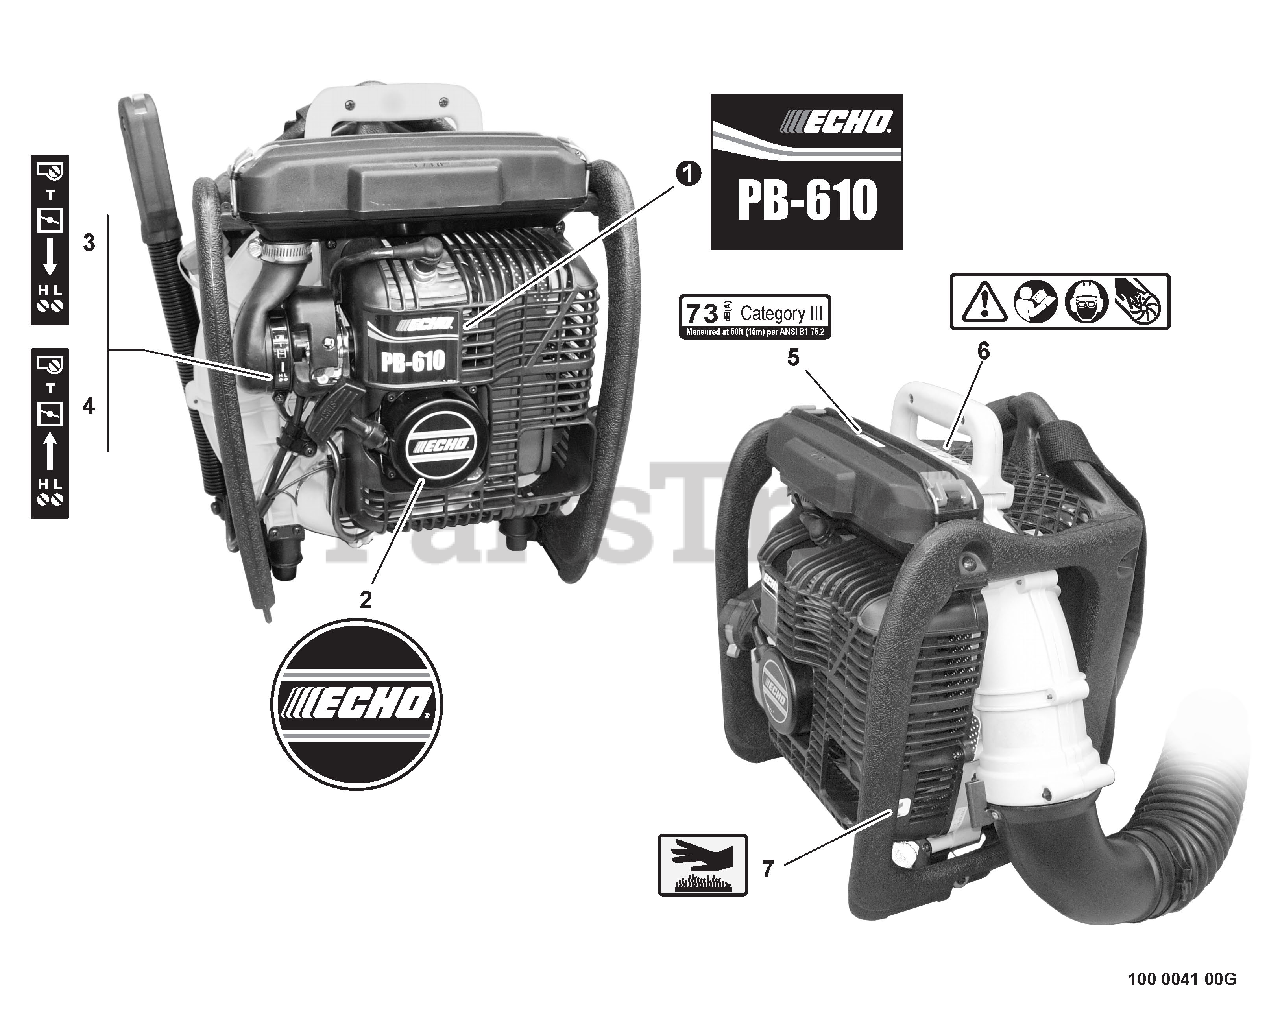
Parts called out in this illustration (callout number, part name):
1	LABEL - CAUTION
2	LABEL - NOISE 72dB(A) CAT III
3	LABEL - HOT SURFACE
4	LABEL - ECHO
5	LABEL - CHOKE
6	LABEL - MODEL PB-620H
7	LABEL - SPARK PLUG -- BPM-8Y
8	LABEL - SPARK PLUG -- BPMR-8Y
